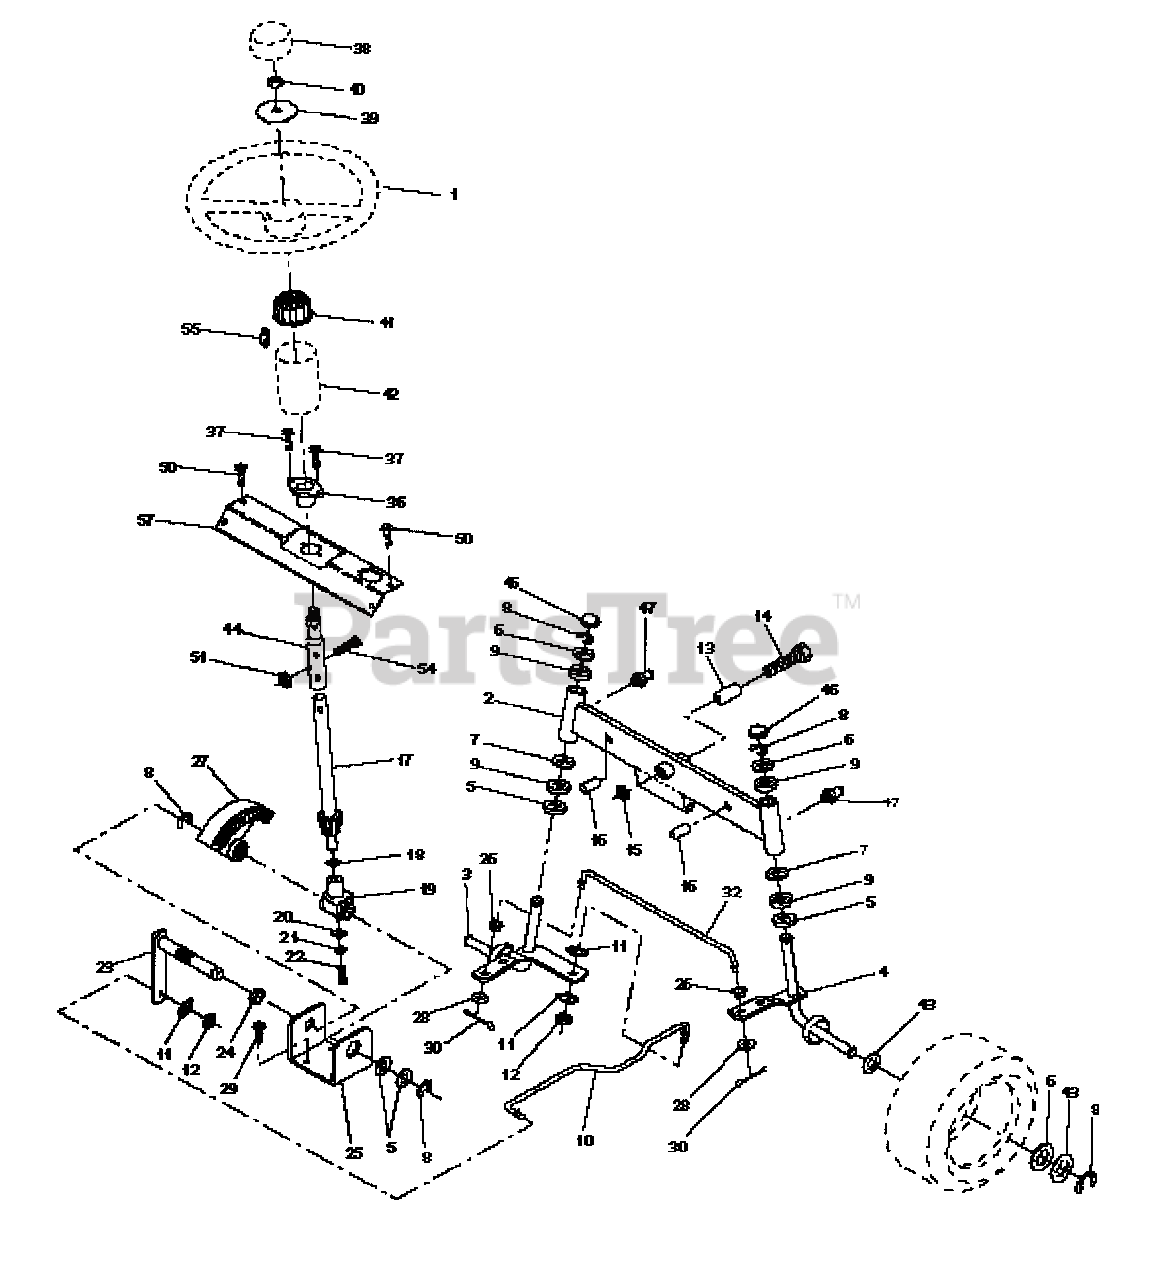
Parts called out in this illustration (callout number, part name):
1	Wheel Steering Auto Black
2	Axle Asm Fr LT W/gzks 38/42
3	Spindle Asm LH
4	Spindle Asm RH
5	Bearing Race Thrust Harden
6	Washer 25/32 X 1-5/8 X 16ga
7	Washer 27/32 X 1-1/4 X 16 Ga
8	Ring Klip #t5304-75
9	Bearing Col Strg Blk
10	Link Drag Sol Ball Jt 20 064
11	Washer Lock Hvy Hlcl Spr 3/8
12	Nut Fin Hex 3/8-24 Unf
13	Spacer Bearing Axle Front
14	Bolt Hex 5/8-11 Unc X 3-1/2
15	Nut Lock Flange 5/8-11 Unc
16	Pin Axle 5/8 X 1 55/1 54 Lg
17	Shaft Asm Strg Private Label
18	Washer Thrust 515x 750x 033
19	Support Shaft
20	Washer Shim 1/4 X 5/8 X 062
21	Washer Lock Hvy Helical 1/4
22	Screw Hex Socket 1/4-20 X 5/8
23	Shaft Asm Pittman
24	Nyliner Snap In
25	Bracket Steering
26	Bushing Link Drag Blk LR
27	Gear Sector 22 Teeth
28	Washer 13/32 X 7/8 X 16ga
29	Screw Thdrol 3/8-16x3/4 Ty-tt
30	Pin Cotter 1/8 X 3/4 Cad
32	Rod Tie Wire Form 19 75 Mech
36	Bushing Strg
37	Screw Slftp #10-16 X 1/2 Ty-b
38	Insert Cap Strg Wh Au Gen Blk
39	Washer 13/32 X 2-3/8 X 8 Ga
40	Nut Lock Center 3/8-24unf
41	Adaptor Wheel Strg 640/ 635id
42	Boot Shaft Steering
43	Washer 25/32 X 1 1/4 X 16 Ga
44	Shaft Extension Steering
45	Ring Klip #t5304-75
46	Cap Spindle Fr Top Blk
47	Fitting Grease
50	Screw Hex Wsh Thdrol 1/4-20 x 3/4
51	Nut Lock Hex w/Insert 5/16-18
54	Bolt Fin Hex 5/16-18 unc x 1-1/4
55	Clip Tinnerman
57	Support Shaft Steering
